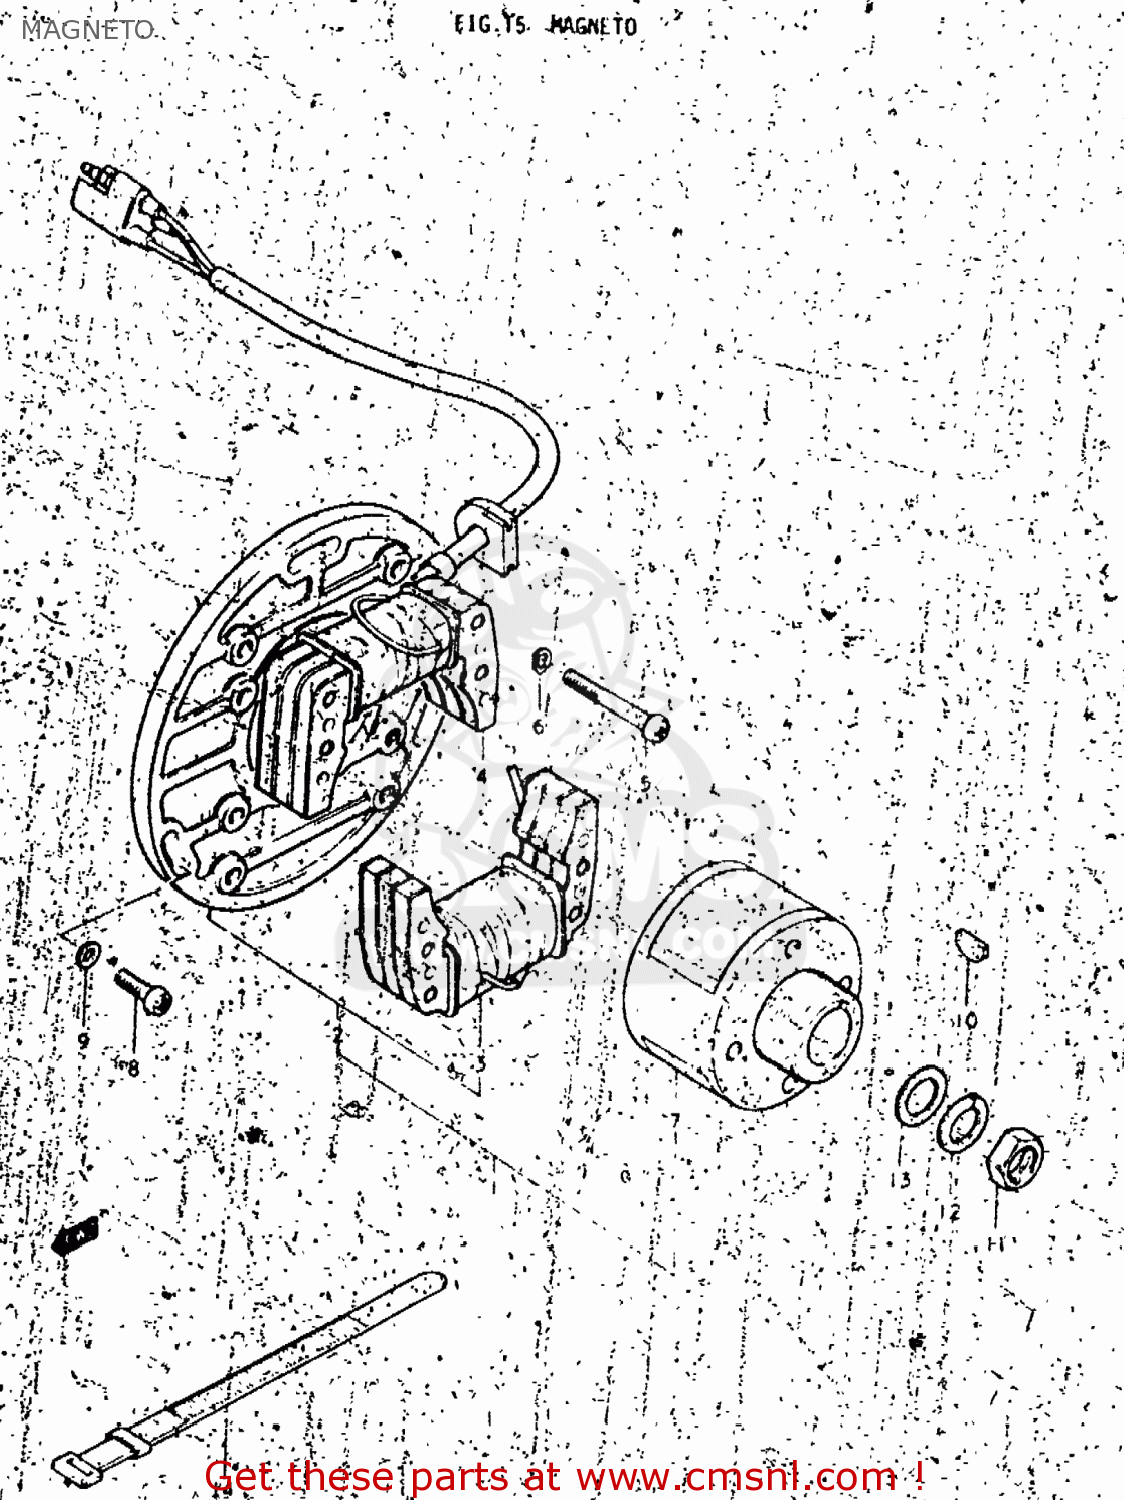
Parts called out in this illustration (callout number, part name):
1	MAGNETO ASSEMBLY
2	STATOR ASSEMBLY
3	COIL
4	COIL
5	SCREW
6	LOCK WASHER
7	ROTOR ASSEMBLY
8	SCREW
9	WASHER
10	KEY 4MM
11	NUT
12	LOCK WASHER
13	WASHER(14X27X3)
14	CLAMP(L:120)
